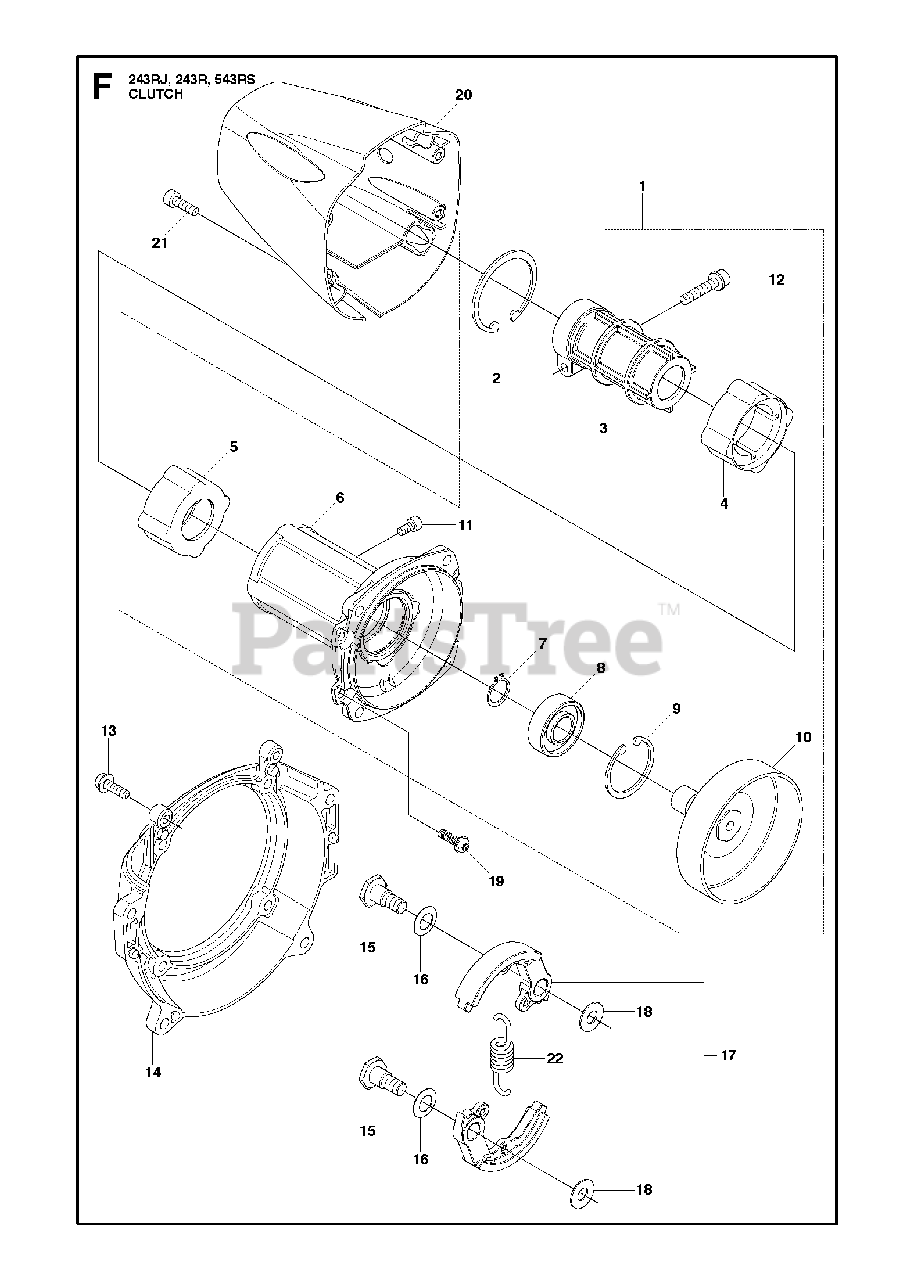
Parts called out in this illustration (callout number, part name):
1	HOUSING ASSY
2	Ring
3	CLAMP
4	ABSORBER
5	ABSORBER
6	HOUSING
7	RING, SNAP, M15 x 1.0
8	BEARING 0600406202
9	SNAP RING
10	DRUM
11	BOLT 08
12	BOLT,TORX M6X30
20	COVER,CLUTCH
